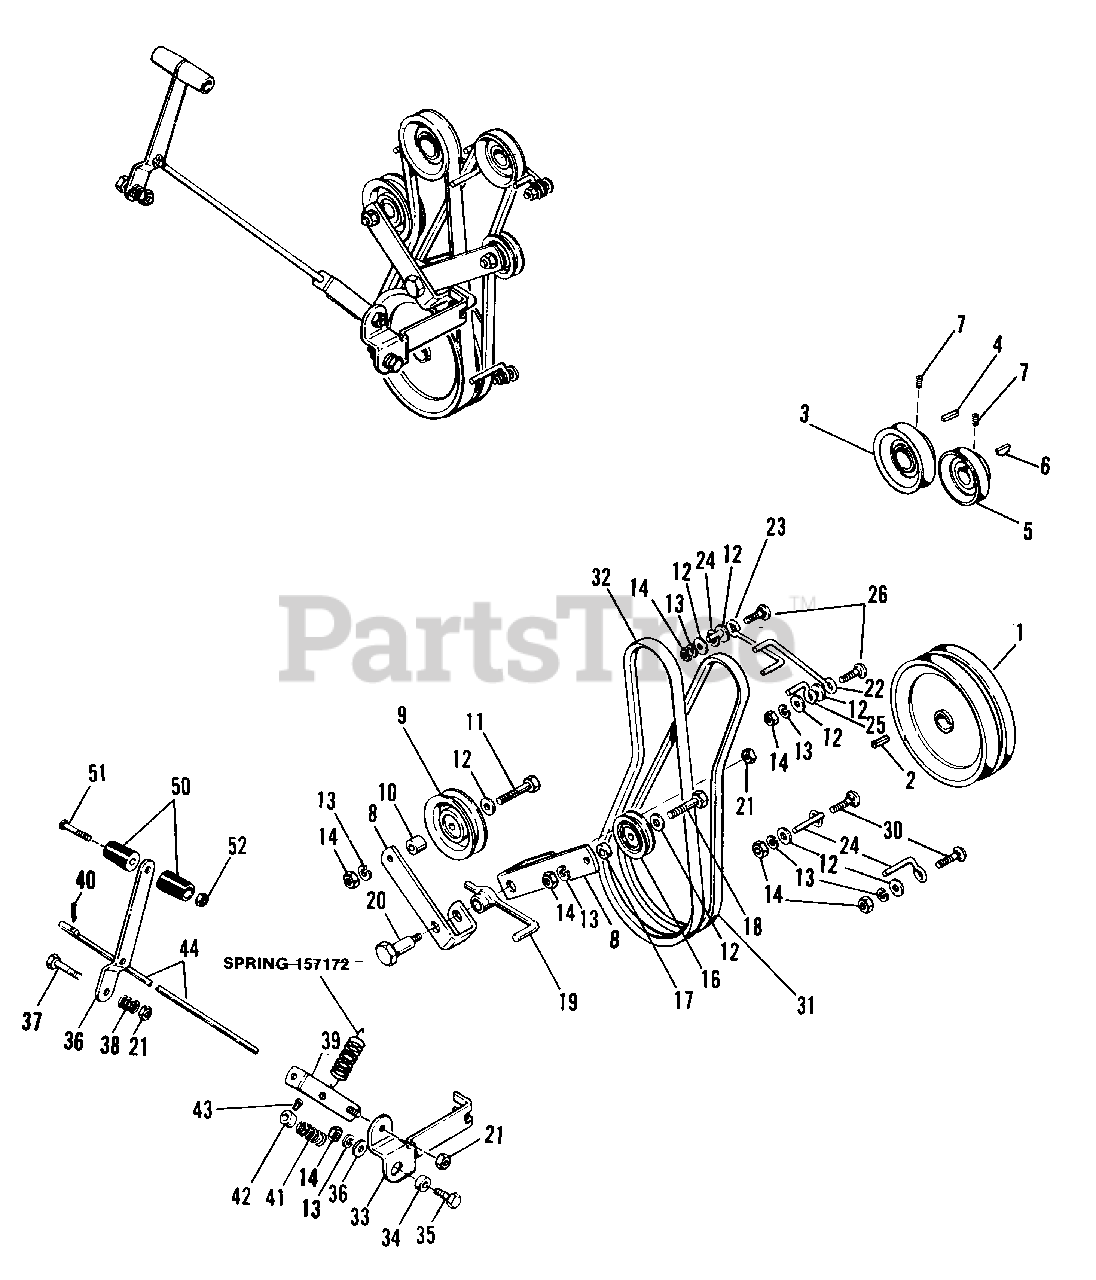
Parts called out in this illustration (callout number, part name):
1	PULLEY, Driven
7	SETSCREW, 5/16-18 x 5/16
8	LEVER, Idler
9	PULLEY, Idler
11	CAPSCREW, Hex
12	WASHER, Plain, 5/16
13	LOCKWASHER, 3/8
14	NUT, Hex, Full, 3/8-16
15	SCREW, Machine, 1/4-20 x 1-1/2
16	PULLEY, Idler
18	CAPSCREW, Hex, 3/8-16 x 1-1/2
19	PIVOT ASSY
20	BOLT, Pivot
21	NUT, Hex, Full, 5/16-18
22	STOP, Belt
24	STOP, Belt
25	STOP, Belt
26	BOLT, Carriage, 3/8-16 x 1-1/4
27	NUT, Hex, Full, 1/4-20
30	BOLT, Carriage, 3/8-16 x 1
31	BELT, V, Reverse
32	BELT, V, Forward
33	BELLCRANK
35	CAPSCREW, Hex, 3/8-16 x 1
37	CAPSCREW, Hex, 5/16 x 1-3/4
39	ROD GUIDE ASSY
40	PIN, Cotter, 3/32 x 3/4
42	COLLAR, Set
43	SETSCREW, 1/4-20 x 3/8
